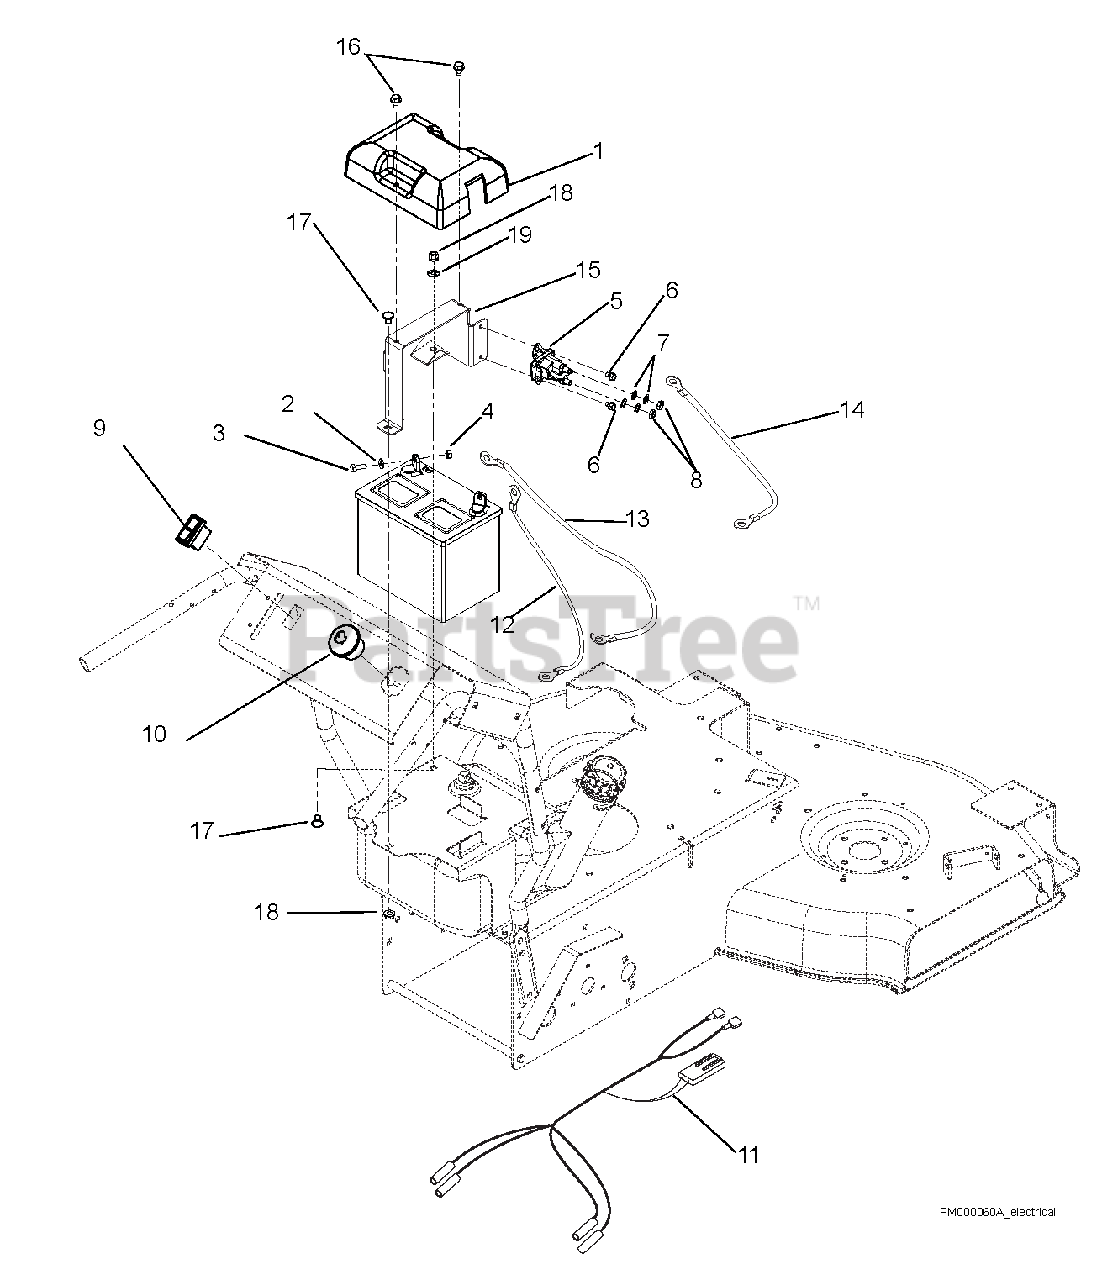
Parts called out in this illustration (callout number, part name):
1	COVER, BATTERY
2	@WSHR-FL-STL.281X.62X.065 YWZC
3	@BLT-HEX .25-20X.75 GR5 YWZC
4	NUT-KEPS .250-20
5	SOLENOID
6	@SCR-TAP .25-20X.37 HWH YWZ TR
7	WSHR-LOCK INT .31 YWZC
8	NUT-JAM .31-24 YWZC
9	SWITCH-ROCKER, MOMENTARY
10	KEYSWITCH-IGNITION 3 POS
10	BRKT, STRIPER MOUNT-RIGHT
11	HARNESS, WAW WIRING
12	CABLE, POS. BAT 18.50"
13	CABLE, GROUND 22.0"
14	CABLE, POS. BAT 6.75"
15	BRKT, BATTERY MOUNT
16	@SCR-TAP .31-18X.50 HWH TR YWZ
17	@BLT-RDHDSQNK .31-18X.50 G5YZ
18	@NUT-LK-TOP-FLG .31-18 YWZC
19	NUT-PUSH .312
